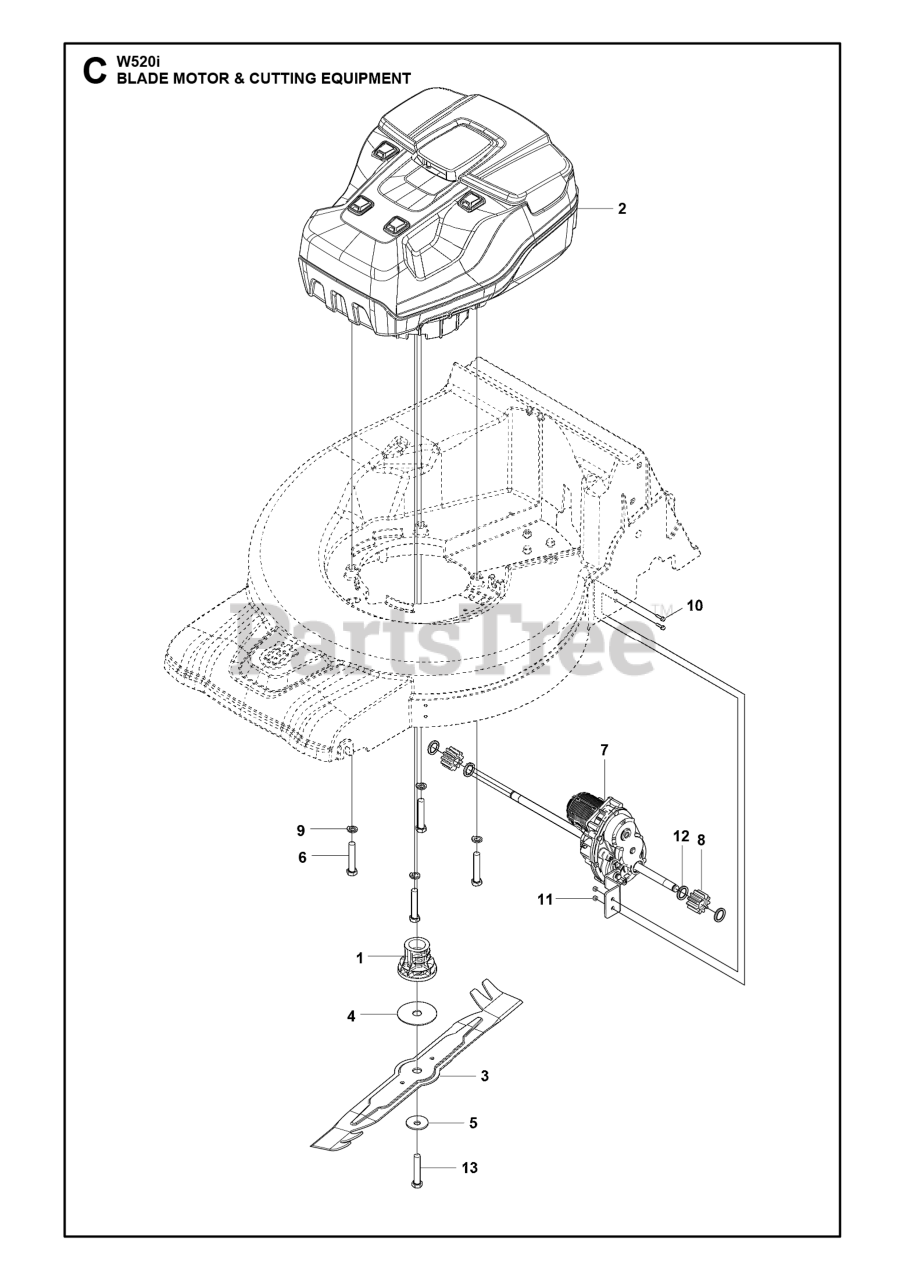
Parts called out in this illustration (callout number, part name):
7	Transmissions
9	Spring Washer
10	SCREW M6S 5X20
